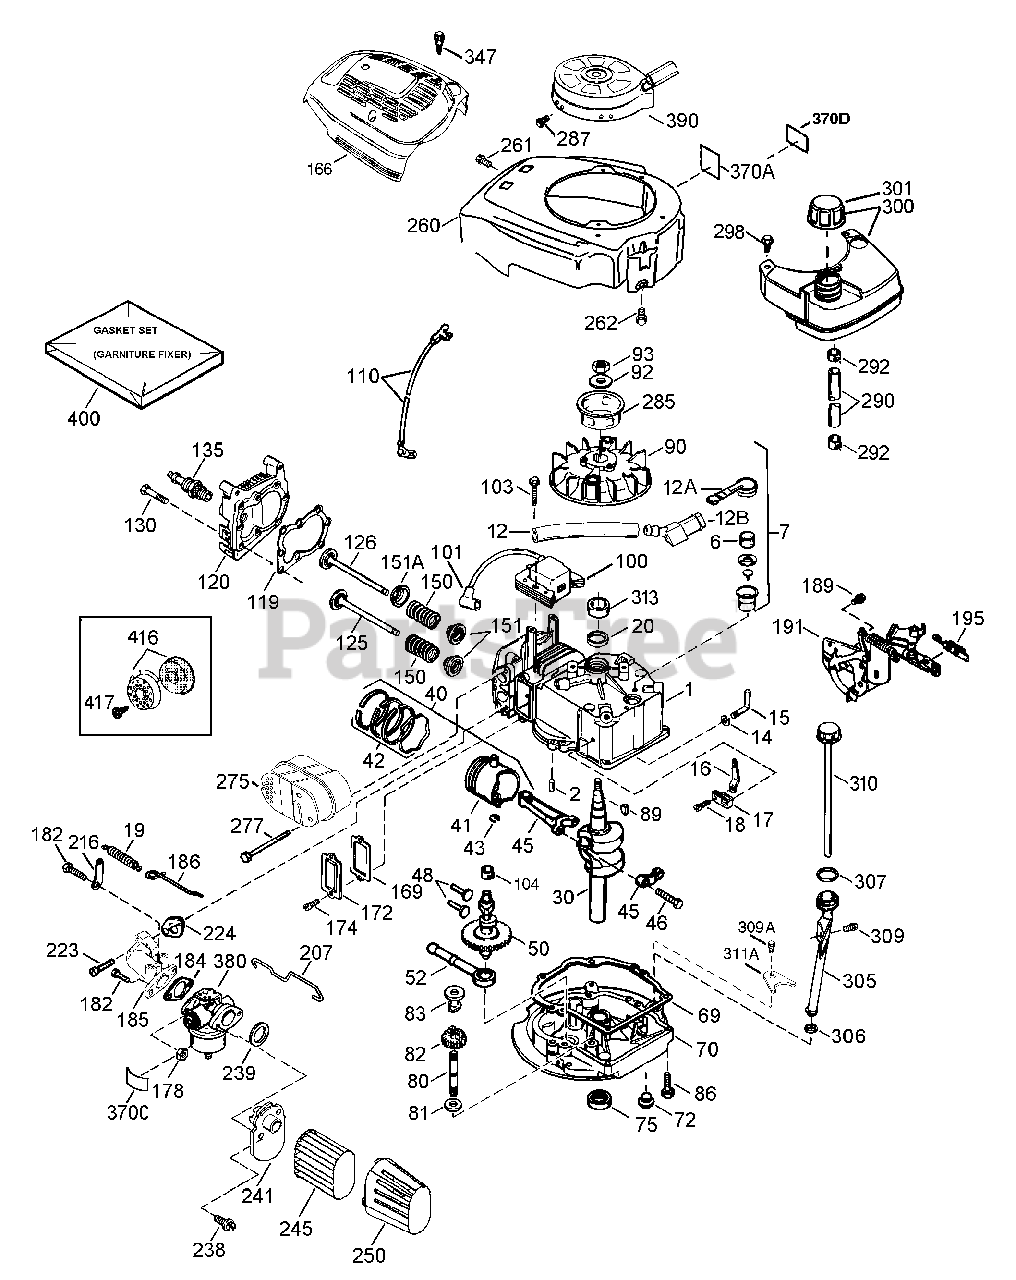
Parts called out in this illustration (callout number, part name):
1	Cylinder (Incl. 2, 20 & 150)
2	Dowel Pin
6	Breather Element
7	Breather Ass'y. (Incl. 6 & 12A)
12	Breather Tube
12A	Breather Cover & Tube (Incl. 12B)
12B	Breather Tube Elbow
14	Washer
15	Governor Rod (Incl. 14)
16	Governor Lever
17	Governor Lever Clamp
18	Screw, T-15, 8-32 x 19/64"
19	Extension Spring
20	Oil Seal
30	Crankshaft
40	Piston, Pin & Ring Set (Std.)
41	Piston & Pin Ass'y. (Std.)(Incl. 43)
42	Ring Set (Std.)
43	Piston Pin Retaining Ring
45	Connecting Rod Ass'y. (Incl. 46)
46	Connecting Rod Bolt
48	Valve Lifter
50	Camshaft (Exhaust MCR)(Inc. 104)
52	Oil Pump Ass'y
69	Mounting Flange Gasket
70	Mounting Flange (Incl. 72-83,306,309A & 311A)
72	Oil Drain Plug
75	Oil Seal
80	Governor Shaft
81	Washer
82	Governor Gear Ass'y. (Incl. 81)
83	Governor Spool
86	Screw, 1/4-20 x 1-1/4"
89	Flywheel Key
90	Flywheel
92	Belleville Washer
93	Flywheel Nut
100	Solid State Ignition
101	Spark Plug Cover
103	Screw, T-15, 10-24 x 15/16"
104	Cam Bushing
110	Ground Wire
119	Cylinder Head Gasket
120	Cylinder Head
125	Exhaust Valve (1/32" OS)(Incl. 151)
125	Exhaust Valve (Std.)(Incl. 151)
126	Intake Valve (Std.)(Incl. 151 & 151A)
130	Screw, 5/16-18 x 1-7/16"
135	Resistor Spark Plug (RJ19LM)
150	Valve Spring
151	Valve Spring Cap
151A	Intake Valve Seal
166	Engine Shroud (Green)
169	Valve Cover Gasket
172	Valve Cover
174	Screw, 10-24 x 9/16"
178	Nut & Lock Washer, 1/4-28
182	Screw, 1/4-28 x 7/8"
184	Carburetor To Intake Pipe Gasket
185	Intake Pipe
186	Governor Link
189	Screw, 1/4-20 x 3/8"
191	S.E. Brake Bracket (Incl. 195)
195	Terminal
207	Throttle Link
216	R.P.M. Adjusting Lever
223	Screw, 1/4-20 x 1"
224	Intake Pipe Gasket
238	Screw, 10-32 x 49/64"
239	Air Cleaner Gasket
241	Air Cleaner Collar
245	Air Cleaner Filter
250	Air Cleaner Cover
260	Blower Housing
261	Screw, 10-24 x 9/16"
262	Screw, 1/4-20 x 1/2"
275	Muffler
277	Screw, 1/4-20 x 2-9/32"
285	Starter Cup
287	Screw, 8-32 x 21/64"
290	Fuel Line
292	Fuel Line Clamp
298	Screw, 10x32 x 35/64"
300	Fuel Tank (Incl. 292 & 301)
301	Fuel Cap Ass'y
305	Oil Fill Tube
306	"O"-Ring
307	"O"-Ring
309	Screw, 10-32 x 1/2"
309A	Screw, 10-24 x 3/4"
310	Dipstick
311A	Hold Down Bracket
313	Spacer
347	Screw, 10-32 x 27/32"
370A	Lubrication Decal
370C	Primer Decal (3 X)
370D	Warning Decal
380	Carburetor (Incl. 184)
390	Rewind Starter (NOTE: This engine could have been built with 590702 starter.)
400	Gasket Set (Incl. Items Marked PK in Notes)
416	Spark Arrestor Kit (Optional)
